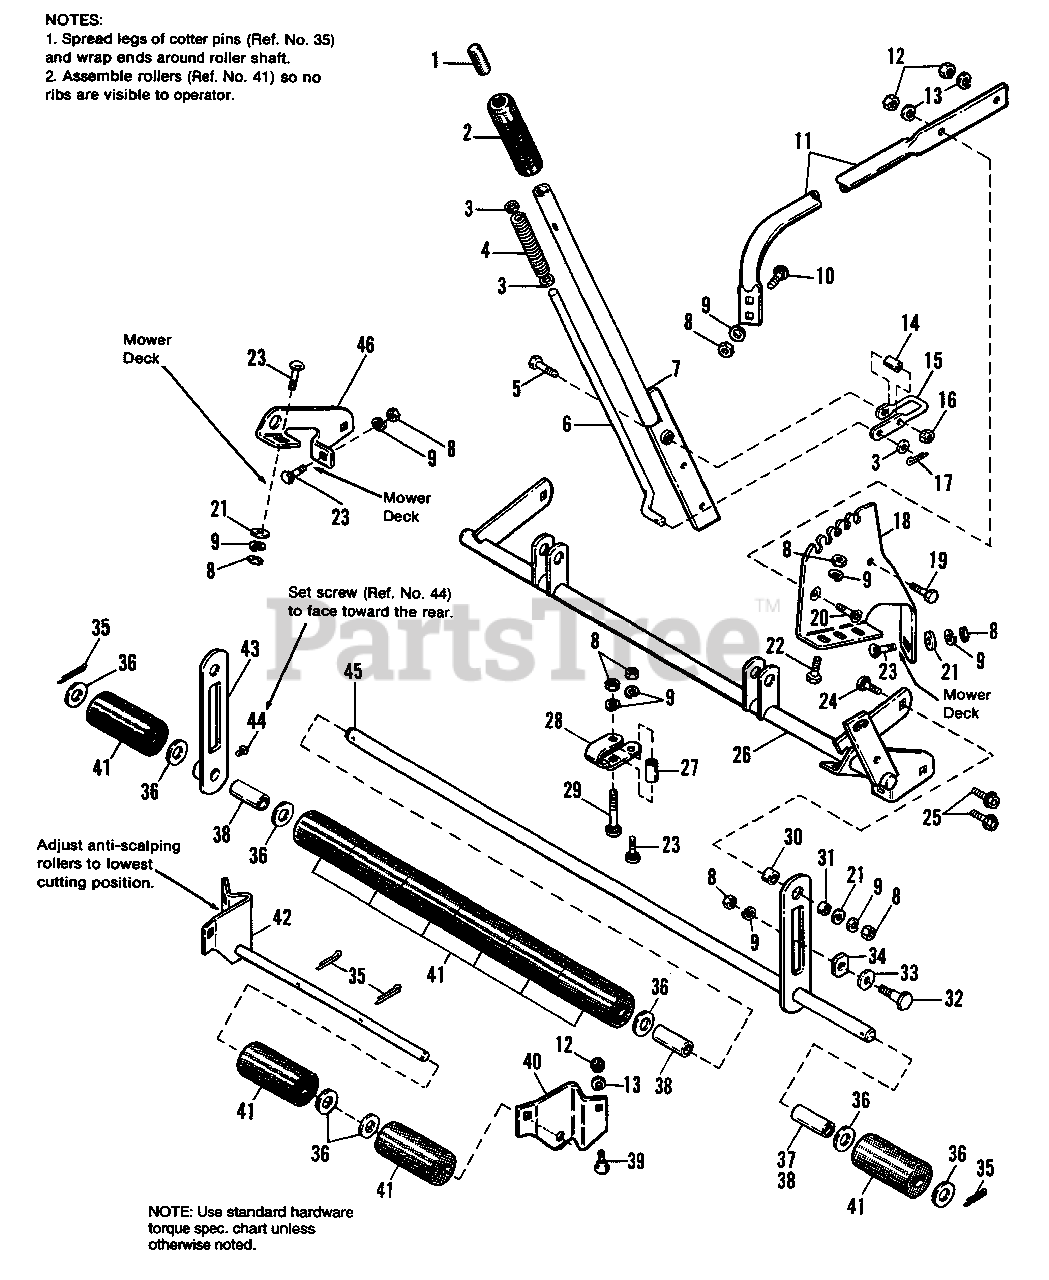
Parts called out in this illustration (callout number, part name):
1	BUTTON, Lift Handle
2	GRIP, Lift Handle
3	WASHER, 5/16
5	CAPSCREW, 5/16-18 x 1-3/4
7	LIFT HANDLE TUBE
8	NUT, Hex, 5/8-16
9	LOCKWASHER, 5/8
10	BOLT, Carriage 3/8-16 x 1, Gr. 5
11	BRACE, Quadrant
12	NUT, Hex, 5/16-18
13	LOCKWASHER, 5/16
16	LOCKNUT, Hex, 5/16-18
17	PIN, Cotter, 1/8 x 3/4
19	CAPSCREW, Hex Hd., 5/16-18 x 1
20	CAPSCREW, Flat Hd., Hex Socket, 5/16-18 x 1
21	WASHER, 13/32
22	CAPSCREW, 3/8-16 x 1
23	BOLT, Carriage, 3/8-16 x 1
24	BOLT, Carriage, 3/8-16 x 1-1/2
25	SCREW, Whizlock 3/8-16 x 5/8
26	SHAFT ASSY., Rocker
27	SPACER
29	BOLT, Carriage, 3/8-16 x 2-1/4
32	BOLT, Shoulder, 3/8-16 X 1.34
33	WASHER, Plain, 1/2 x 1-1/4 x 3/8
35	PIN, Cotter, 3/16 x 1
36	WASHER,21/32
37	SPACER
38	SPACER
39	BOLT, Carriage, 5/16-18 x 3/4
40	BRACKET, Roller, L.H.
42	BRACKET & SHAFT ASSY.
43	BAR ASSY., Roller
44	SETSCREW, Sq. Hd., 5/16 x 1/2
45	SHAFT ASSY., Roller
46	BRACKET, Roller, R.H.
